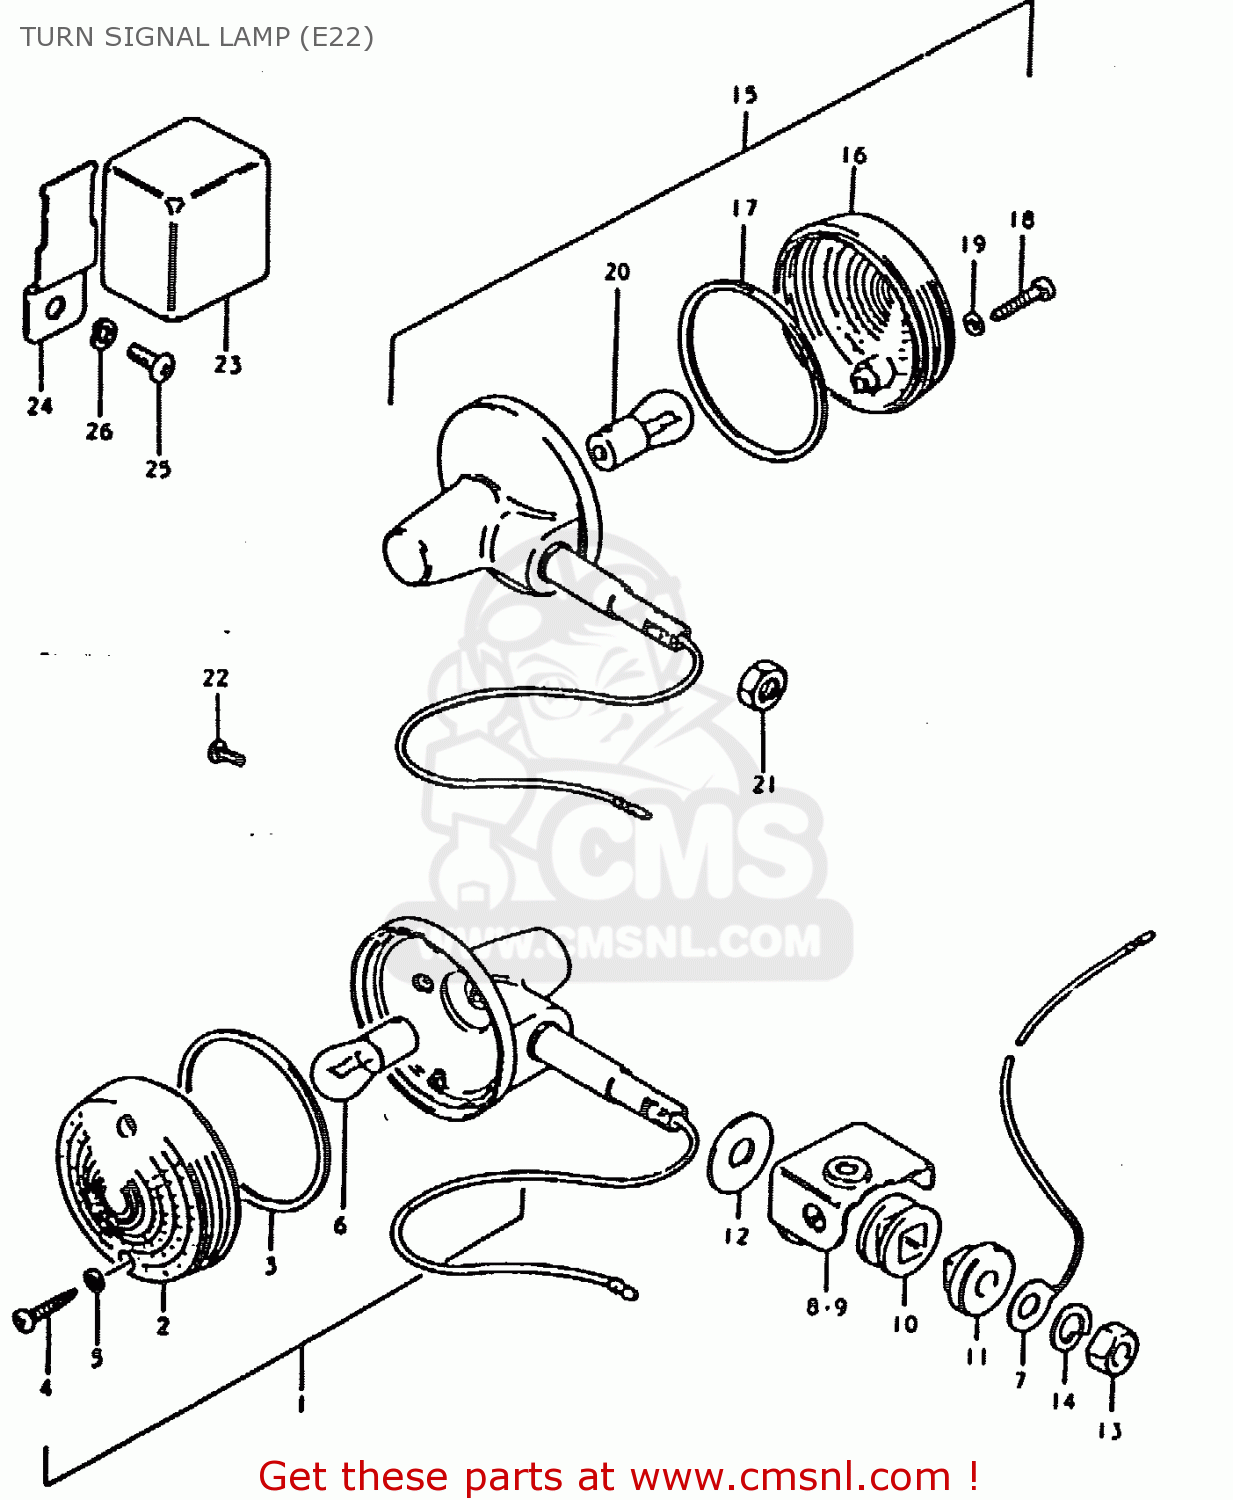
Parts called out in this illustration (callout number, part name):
1	LAMP, FRONT TURN SIGNAL
2	LENS
3	GASKET (NAS)
4	SCREW
5	GASKET (NAS)
6	BULB (6V,21W)
7	LEAD WIRE,EARTH
8	BRACKET, FRONT TURN SIGNAL LAMP RH
9	BRACKET, FRONT TURN SIGNAL LAMP LH
10	CUSHION
11	SPACER,RR TURNSIGNAL LAMP
12	WASHER (10.5X30X2.3)
13	NUT
14	LOCK WASHER
15	LAMP, REAR TURN SIGNAL
16	LENS
17	GASKET (NAS)
18	SCREW
19	GASKET (NAS)
20	BULB (6V,21W)
21	NUT
22	SCREW 5X6
23	RELAY, TURN SIGNAL
24	BRACKET,TURN SIGNAL RELAY
25	SCREW 6X12
26	LOCK WASHER
